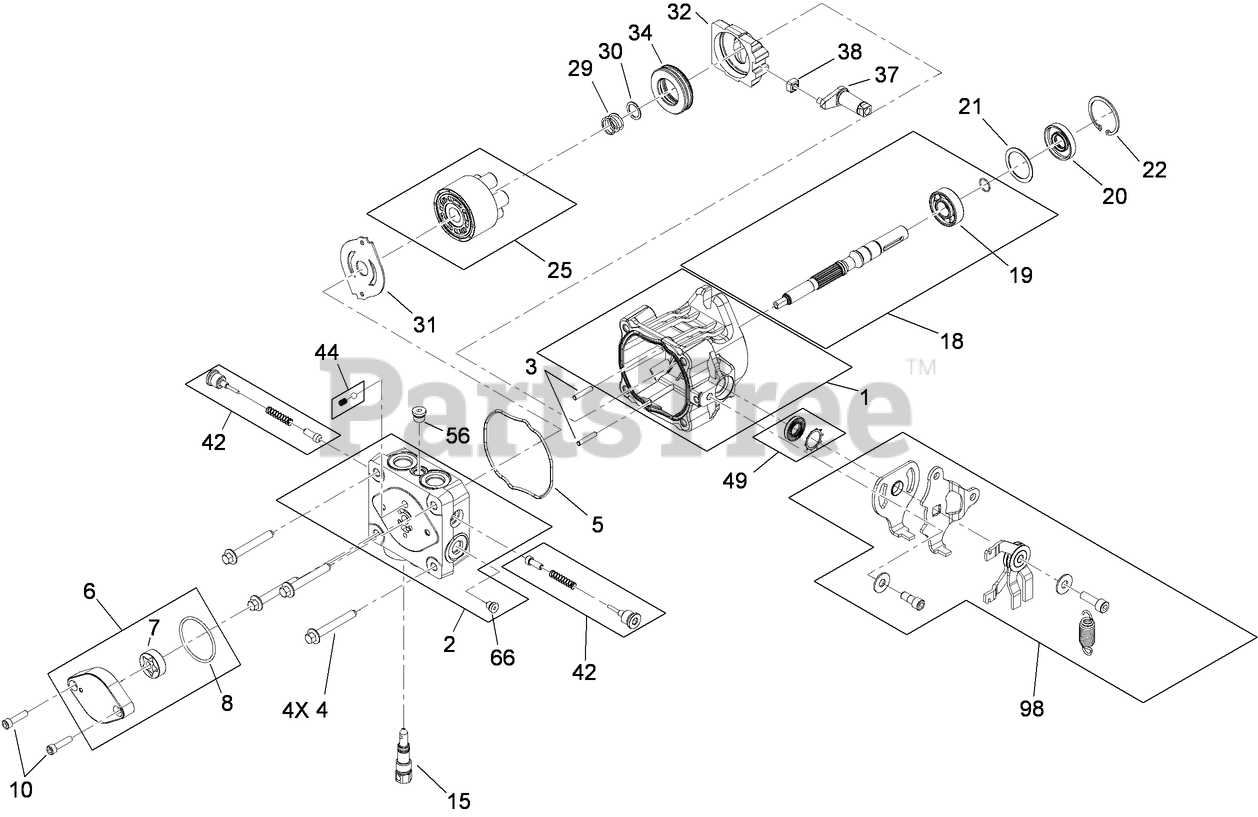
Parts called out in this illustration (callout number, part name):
1	HOUSING KIT
2	END CAP KIT (W/POPPETS)
3	PIN-HEADLESS, STRAIGHT
4	BOLT-HF
5	O-RING
6	CHARGE PUMP KIT
7	GEROTOR ASM
8	O-RING
10	CAPSCREW
15	BYPASS VALVE KIT
18	INPUT SHAFT KIT
19	BEARING-BALL
20	SEAL-LIP
21	SPACER
22	RING-RETAINING
25	CYLINDER BLOCK KIT
29	SPRING-BLOCK
30	WASHER-THRUST
31	Plate-Valve
32	SWASHPLATE-VARIABLE
34	BEARING-THRUST
37	ARM-TRUNNION, TAPERED SQUARE
38	GUIDE-SLOT
42	VALVE-CHECK (W/POPPET)
44	CHARGE RELIEF VALVE KIT
49	TRUNNION SEAL KIT
56	PLUG-HSH
66	PLUG-HSH
98	KIT-RETURN
